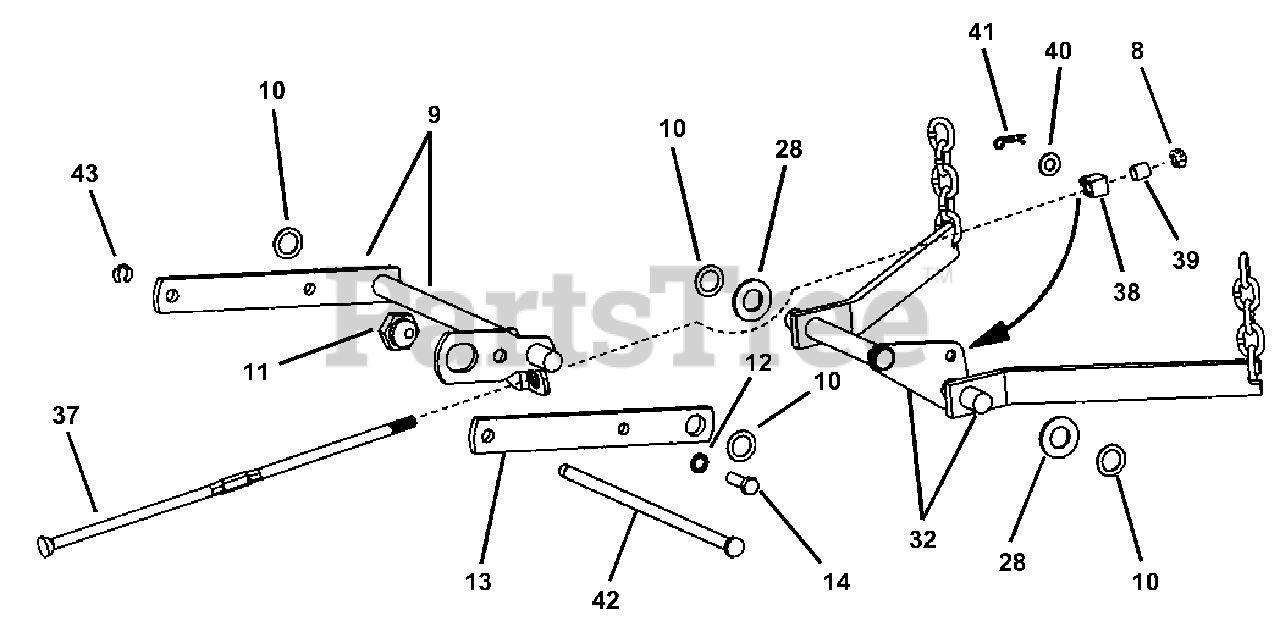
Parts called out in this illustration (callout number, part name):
8	NUT, 3/8-16 Hex Center Lock
9	ARM, Front Lift (weldment)
10	WASHER, 3/4"
11	ECCENTRIC, Leveling (3/8-24 thread)
12	WASHER, 3/8" Internal Tooth Lock
13	ARM, Front Lift
14	SCREW, 3/8-24 x 1-1/4" Hex Head Cap
28	WASHER, 25/32" Flat
32	ARM, Rear Lift (weldment)
37	ROD, Cutting Deck Timing
38	SWIVEL, Brake Link PM
39	SPACER, 25/64"
40	WASHER, 3/8"
41	HAIRPIN, #13
42	ROD, Deck Support
43	RING, 7/16" Snap
